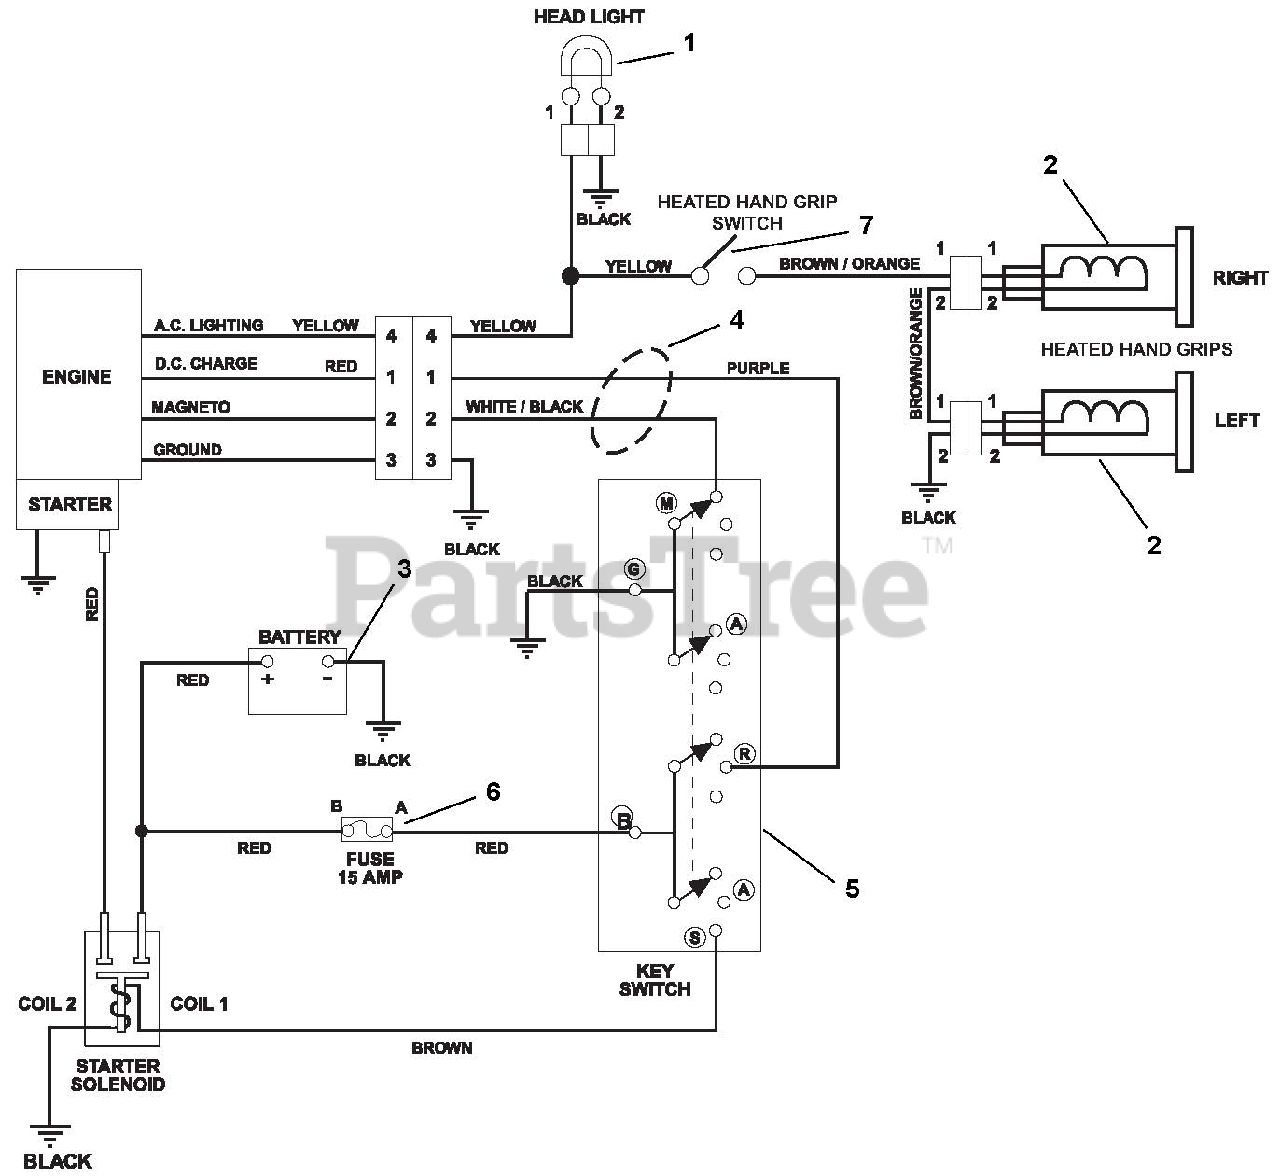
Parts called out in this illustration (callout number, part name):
1	HEADLIGHT ASSY, HALOGEN 20W
2	HEATED GRIP, MAGURA
3	Battery
4	HARNESS,WIRING-LT,HW 12V
5	SWITCH ASSEMBLY
6	FUSE, 15 AMP.
7	SWITCH, ON/OFF
